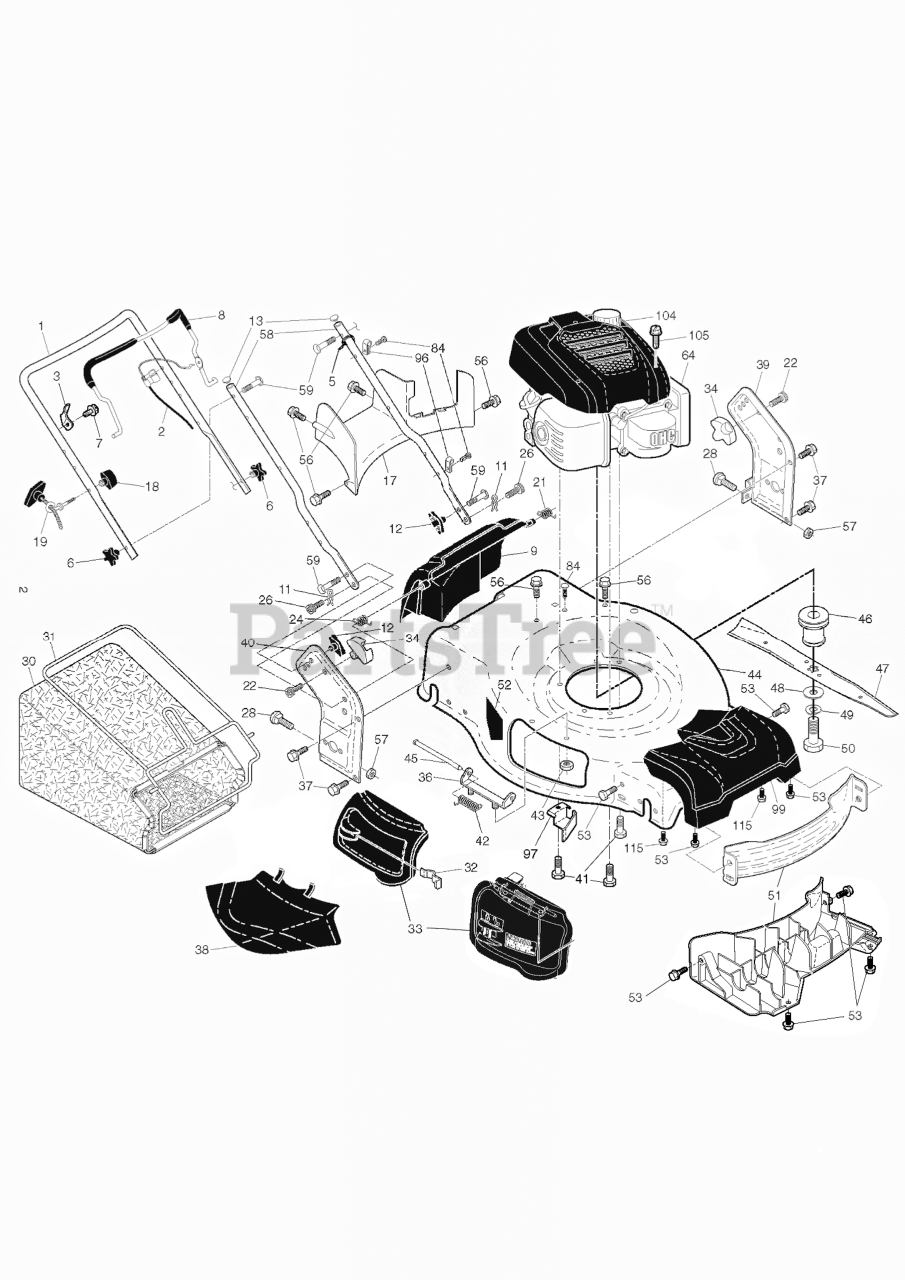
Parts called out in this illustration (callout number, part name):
1	HANDLE.UP.3POS.BS.AW2.GREY
2	CABLE MZR (ZONE) 48.5 CONDUIT
2	CABLE.MZR.ZONE.CONTROL
2	CABLE.MZR.50.SNAP-IN
3	BRACKET.UPSTOP.RT
5	TIE GUIDE
6	KNOB.HANDLE.PLASTIC.STAR.BLACK
7	SCREW
8	BAIL.OM.ERGO.BENT.MZR.ORAN.668
8	BAIL.OVER.MOLD.ERGO.MZR.ORANGE
9	DOOR.REAR.ASM.22+.HUSQ.F/RG.CE
11	COTTER.HAIRPIN.DOOR/HANDLE.PIV
12	KNOB, DEFLECTOR
13	PLUG.PLASTIC.7/8".14-20.GAUGE
17	BAFFLE.REAR.22+RGD.AWD.PLASTIC
18	T-KNOB.NEW ROPE GUIDE
19	GUIDE.ROPE.BLK.ZINC.CHROM
21	SPRING.LH.BLACK
22	SCREW.PAN.HEAD.#10
24	SPRING.RH.GRAY
26	SCREW,DOOR/HANDLE.PIVOT
28	BOLT.CARRIAGE.LN.5/16-18X.5/8
28	BOLT
30	GBAG.BA85028ER.GRY/ORG
31	FRAME.GBAG.22+.BLK
32	LATCH.DOOR.ZINC
33	DOOR ASSY KIT.MULCH DOOR.CE 22
33	DOOR.MULCH.22 PLUS.HUSQ.GREY
34	BRACKET.GRASSBAG.ATTACHING.BLK
36	BRACKET.ASM.HINGE.21.FWGD.
37	BOLT.5/16HEX.WHS.HD
38	DEFLECTOR.CLIPPING.22.BLACK
39	BRACKET.ASM.HANDLE.LT.22+.GREY
40	BRACKET.ASM.HANDLE.RT.22+.GREY
41	BOLT 3/8-16X1-1/8
42	SPRING.TORSION
43	NUT.FLANGE.1-4-20-SERR
44	HOUSING.22+RGD.MCUT.WO.HUS.TRI
44	KIT.HSG.22+RGD.MC.WO.668.CE
45	ROD.HINGE.21
46	ADAPTER.BLADE.25MM.3MPH
46	ADAPTER BLADE, 25 MM 22+ AWD/
47	BLADE 22 4-N-1 2PIN 5STAR BLK
47	BLADE.22.MULCH.STANDARD
48	WASHER,HARDEN
49	LOCKWASHER
50	SCREW, HEX HD 3/8-24 X 1-3/8
51	BAFFLE.FRONT.22.PLUS
51	BAFFLE.FRONT.22+PLASTIC.(2 2)
52	DECAL.INTERNATIONL.CUTFINGER
53	SCREW.HI-LO.5/16 X.75
53	SCREW.HI-LO. 5/16 X 1.00
53	BOLT.5/16HEX.WHS.HD
56	SCREW.HX.13X.750
57	NUT.FLANGE.5/16
58	HANDLE.LOWER.22+BT.2PC.GRY
58	HANDLE.LOWER.ASM.W/PLUG.22+.49
59	BOLT, HANDLE 5/16-18X1.75
84	FASTENER.PUSH.O.250X0.783
96	CLIP.CABLE.BLK
97	BRACKET.BELT.GUIDE.22+.BZP
99	COVER.ASM.FRONT.SHROUD.HUSQ.
99	COVER.ASM.FRONT.HUSQ.22+RGD
104	SHROUD.ASM.HONDA.HUSQVARNA
105	SCREW.SHROUD.HONDA
115	SCREW.HI-LO. 5/16 X 1.00
